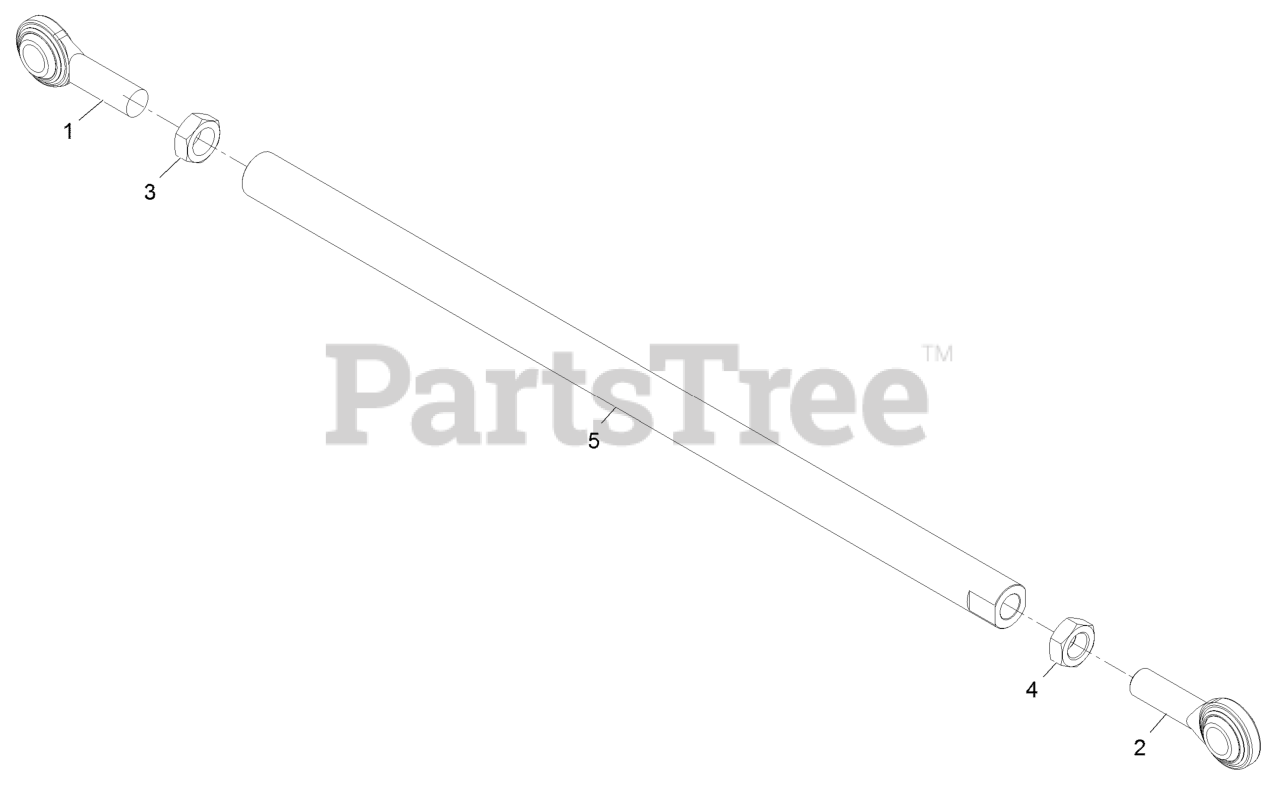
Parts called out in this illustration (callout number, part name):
1	BALLJOINT-SPHERICAL
2	BALLJOINT-SPHERICAL
3	NUT-JAM
4	NUT-JAM
5	LINK-HEIGHT OF CUT
